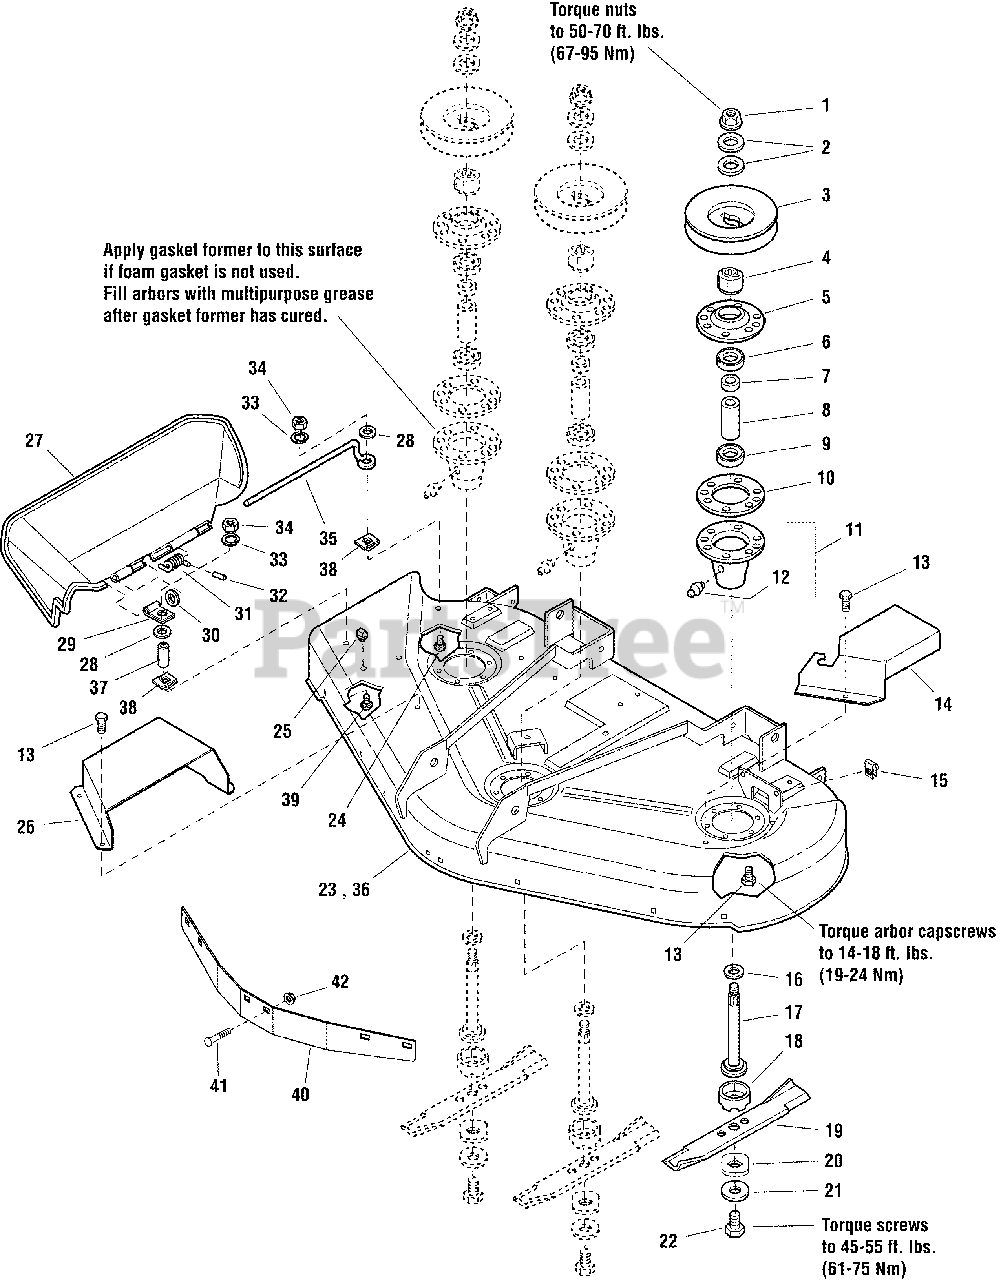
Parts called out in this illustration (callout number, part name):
1	NUT, HEX FLANGE, 9/16-18
2	WASHER, Bellville, 9/16
3	PULLEY
4	HUB
5	COVER, ARBOR HOUSING
6	BEARING, BALL, 3/4 X 1-3/4 X 5/8
7	SPACER, 21/32 X 3/4 X 5/8
8	SPACER, 11/16 X 5/32 X 2-11/16
9	BEARING, BALL, 11/16 X 1-9/16 X 15/32
10	SEAL, FOAM
11	ARBOR HOUSING ASSEMBLY
12	FITTING, GREASE
13	BOLT TAPTITE, 5/16-18 X 3/4
14	COVER, ARBOR, LH
15	BODY CLIP, 5/16-18
16	WASHER, 9/16, BLACK
17	SHAFT, ARBOR
18	SHIELD, GRASS, LOWER
19	BLADE, MOWER, 16-1/8
19	BLADE, MOWER, 18-1/8
20	WASHER, HEX, 11/16 X 2
21	WASHER, SPRING, 15/32, BLACK
22	BOLT, 7/16-14 X 1-1/4
23	DECK SHELL W/DECALS, 44" MOWER
23	DECK SHELL W/DECALS, 50" MOWER
24	CARRIAGE BOLT, 1/4-20 X 7/8
25	PLUG, HOLE
26	COVER, ARBOR, RH
27	DEFLECTOR, PLASTIC
28	WASHER, 1/4, BLACK
29	CLAMP
30	WASHER, 5/16, BLACK
31	SPRING
32	VINYL CAP
33	WASHER, LOCK, 1/4
34	NUT, HEX, 1/4-20
35	ROD, DEFLECTOR
36	DECK SHELL W/ DECALS, 50 - SNP 400Z
37	SPACER-0.328IDX0.499ODX0.625LG PM
38	NUT-PUSH FOR .250 DIA THREAD .500 OD BLK
39	BOLT, CARRIAGE, 1/4-20 X 1.25, GD5,BLACK
40	BAFFLE - FRONT 44/50 - BLACK
41	BOLT, 5/16-18 X 3/4 CARRIAGE
42	NUT, 5/16-18 HEX NYLOCK FLANGE
